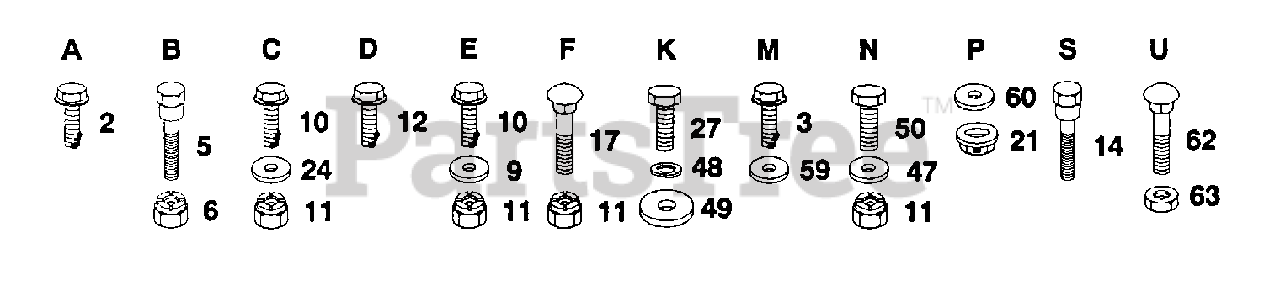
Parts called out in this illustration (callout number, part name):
2	SCREW
3	SCREW GTV
9	WASHER
12	SCREW LT
14	"BOLT,SHOULDER"
17	BOLT
21	PAL NUT LT
27	BOLT
47	WASHER
48	LOCKWASHER
49	WASHER
50	BOLT
59	WASHER
60	WASHER PM
62	BOLT
